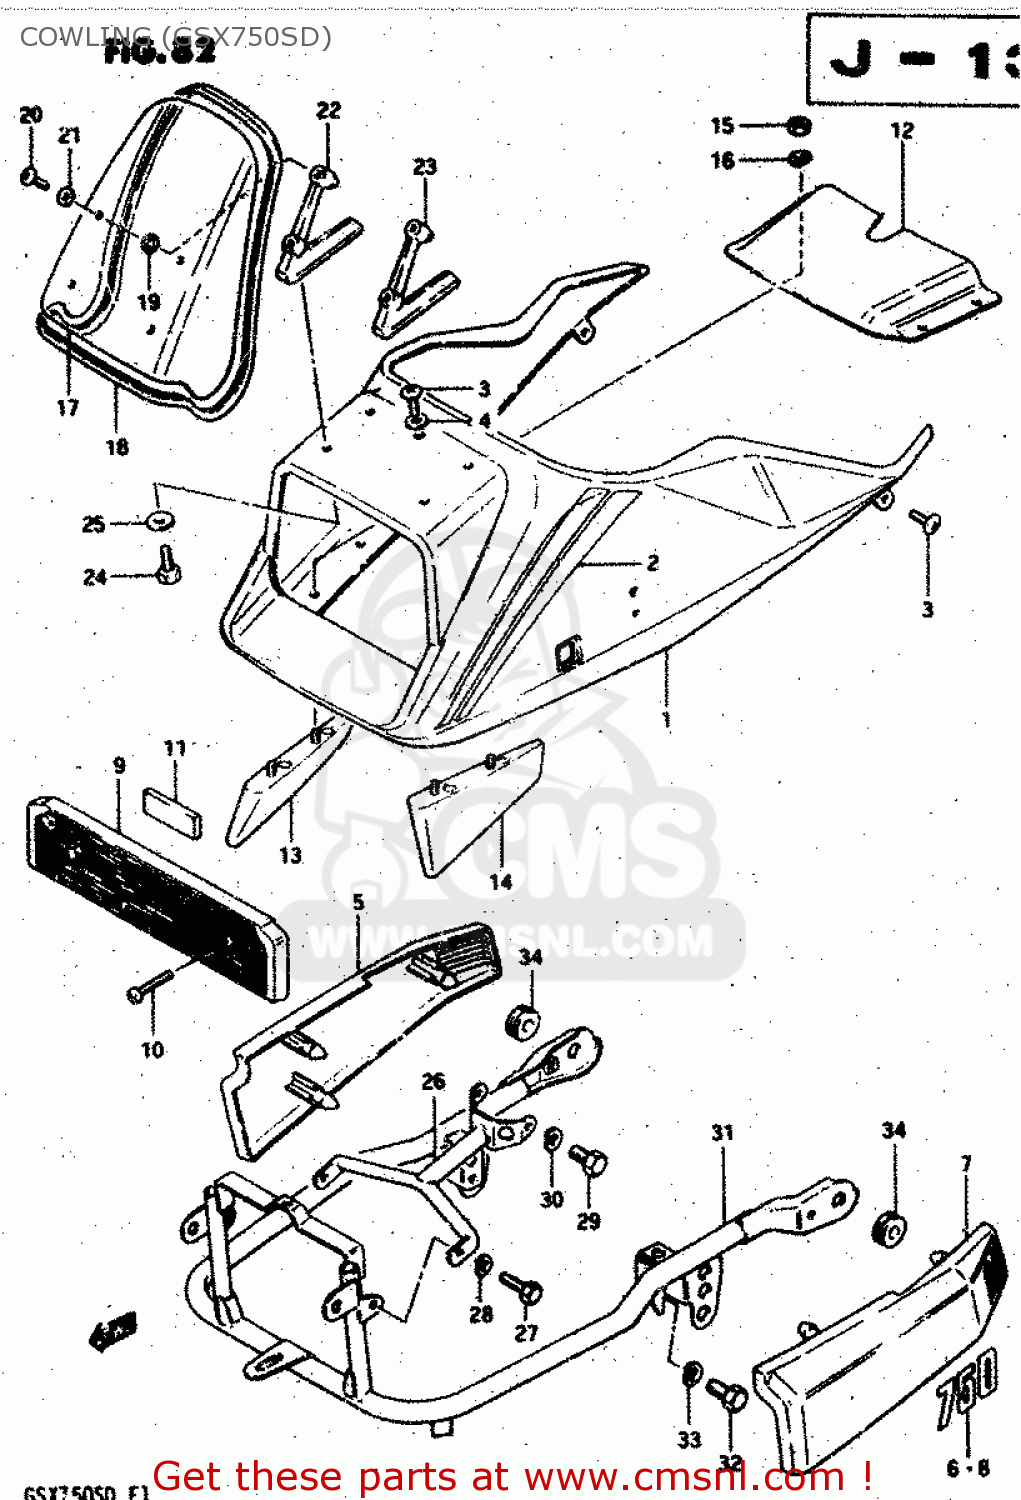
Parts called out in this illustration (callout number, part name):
1	BODY, COWLING (BLACK/SILVER)
2	TAPE SET
3	SCREW 6X12
4	WASHER
5	COVER,COWLING,RIGHT
6	EMBLEM,FRAME COVER
7	COVER,COWLING,LEFT
8	EMBLEM,FRAME COVER
9	COVER,COWLING LOWER
10	SCREW
11	CUSHION
12	COVER,COWLING LOWER FR
13	WING,COWLING RH
14	WING,COWLING LH
15	NUT
16	LOCK WASHER
17	WINDOW,COWLING
18	MOLD,COWLING
19	CUSHION
20	SCREW
21	WASHER(5.2X11X1)
22	BRACE,COWLING WINDOW RH
23	BRACE,COWLING WINDOW LH
24	BOLT
25	WASHER(6.5X16X1.2)
26	BRACKET,COWLING UPPER
27	BOLT
28	LOCK WASHER
29	BOLT 8X12
30	LOCK WASHER
31	BRACE,COWLING RR
32	BOLT
33	LOCK WASHER
34	CUSHION
